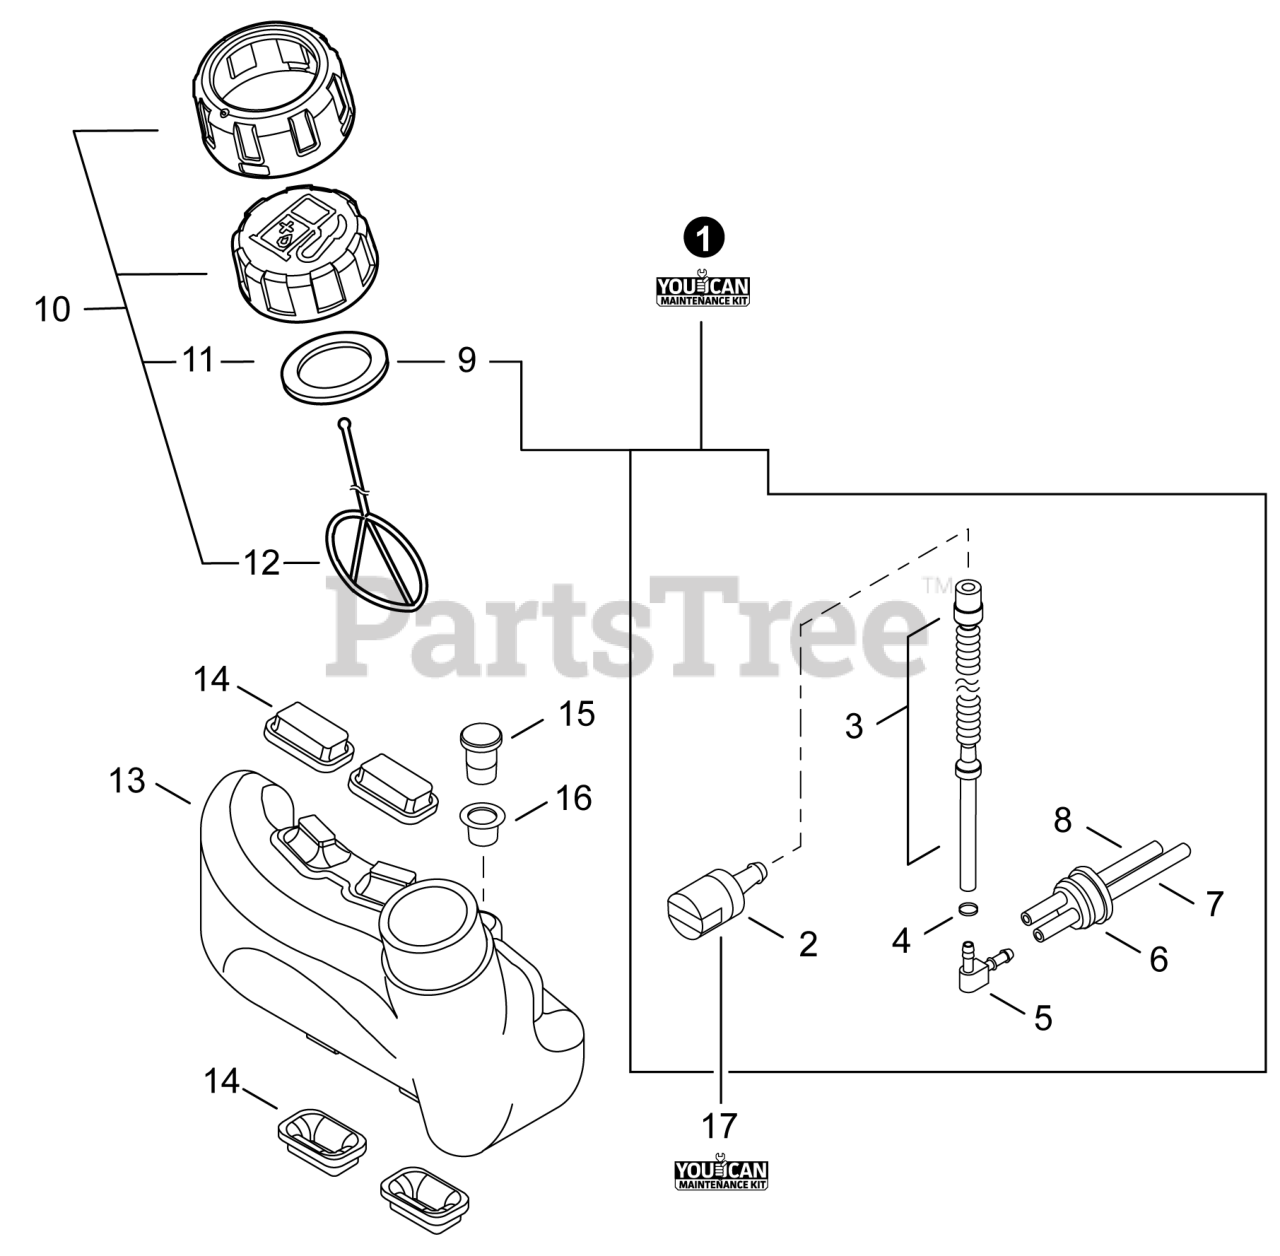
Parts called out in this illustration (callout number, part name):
1	FUEL SYSTEM KIT - YOUCAN?
2	FILTER, FUEL
3	PIPE, FUEL
4	CLIP 6.5 MM
5	CONNECTOR, PIPE
6	GROMMET, FUEL
7	PIPE, FUEL 3x5x83 BLACK
8	PIPE, FUEL 3x6x85 YELLOW
9	GASKET, FUEL CAP
10	CAP ASSY, FUEL
11	GASKET, FUEL CAP
12	CONNECTOR, CAP L= 123
13	TANK, FUEL
14	CUSHION
15	VENT ASSY
16	GROMMET, FUEL
17	TUNE-UP KIT - YOUCAN?
